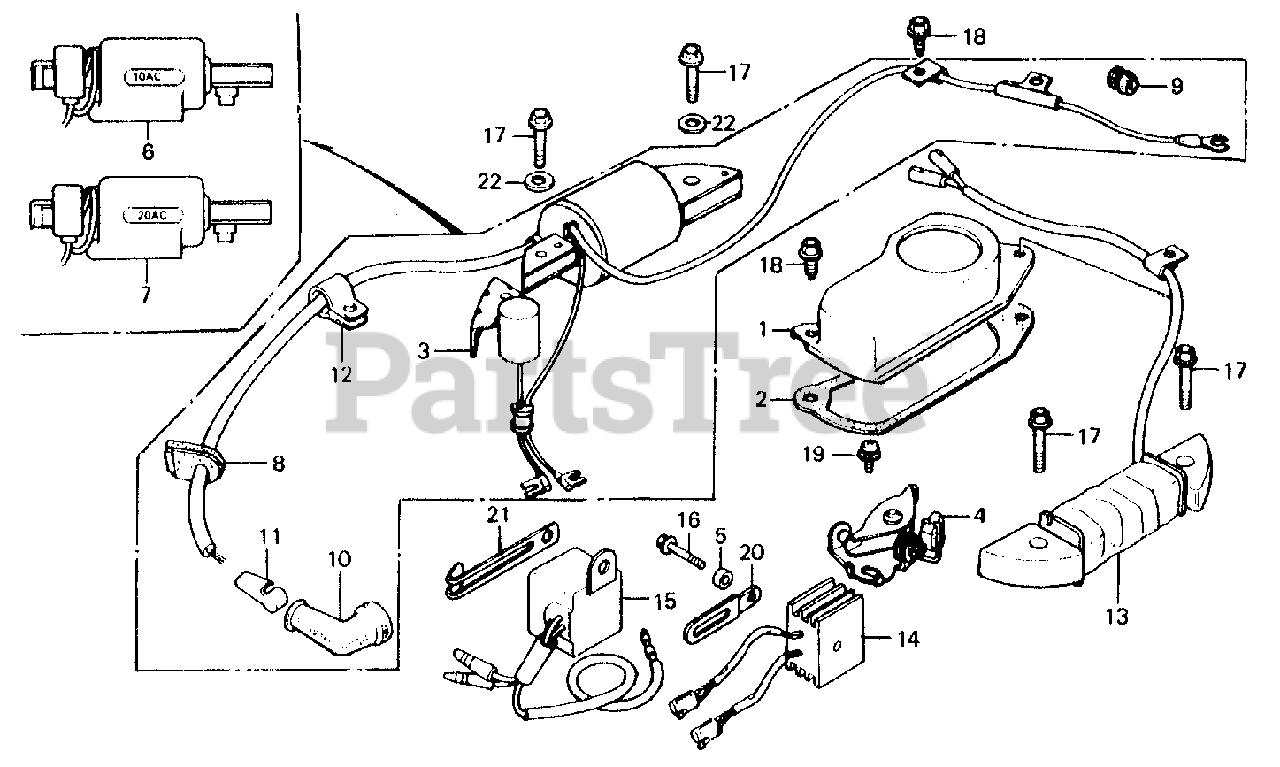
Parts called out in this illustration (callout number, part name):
1	COVER, BREATHER
2	GASKET, COVER
4	POINTS ASSY.
6	COIL ASSY., IGNITION
8	GROMMET, WIRE
9	GROMMET, PRIMARY WIRE
10	CAP, IGNITION (SUMITOMO)
10	CAP, IGNITION (TOYO)
11	TERMINAL, PLUG
12	CLAMP, IGNITION WIRE
17	BOLT, FLANGE (6X32)
18	BOLT, FLANGE (5X14)
19	SCREW-WASHER (5X12)
22	WASHER, PLAIN (6MM)
